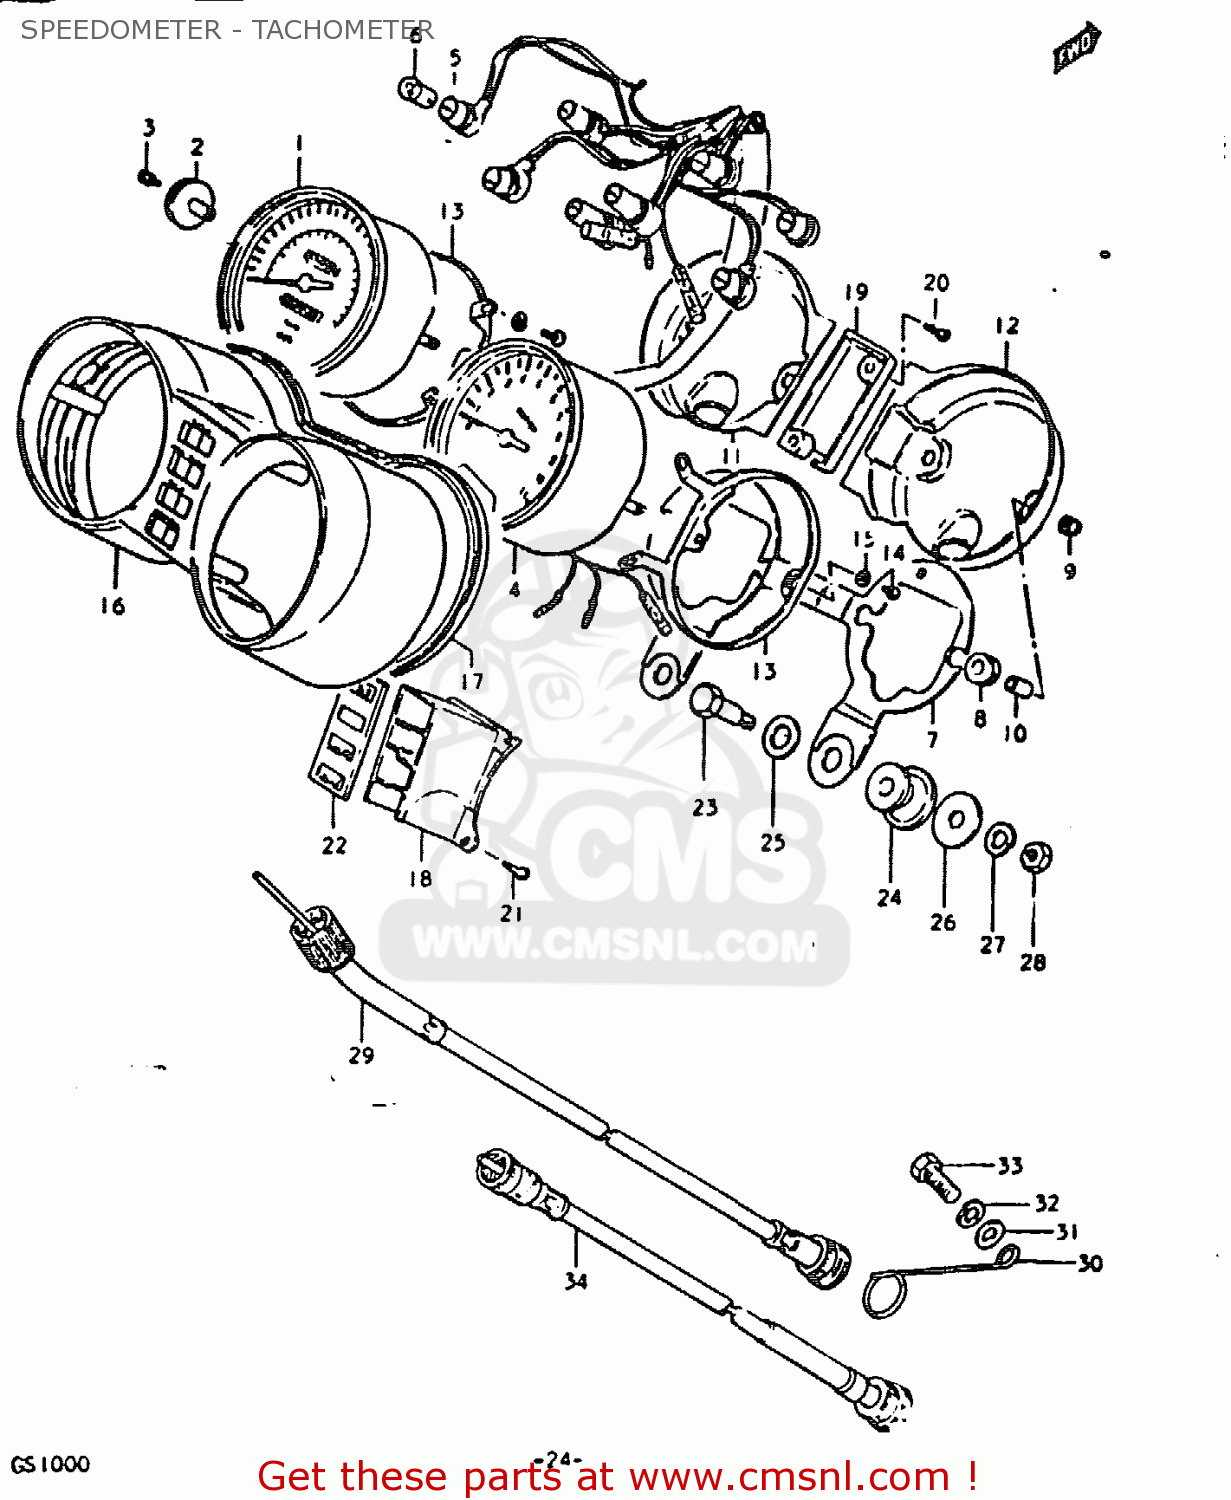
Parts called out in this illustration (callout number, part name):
1	SPEEDOMETER
2	KNOB,TRIP METER
3	SCREW
4	TACHOMETER
5	SOCKET,SPEEDOMETER
6	BULB(12V3.4W,STANLEY,A72A)
7	BRACKET,COMBINATION METER
8	CUSHION,SPEEDOMETER
9	NUT
10	SPACER,SPEEDOMETER
11	COVER,METER,UNDER
12	PLATE,TACHOMETER UNDER
13	HOLDER,METER
14	SCREW
15	LOCK WASHER
16	CASE,METER
17	CUSHION,METER CASE
18	CASE,PILOT BULB
19	PLATE,PILOT BULB CASE
20	SCREW,PILOT CASE
21	SCREW,SPEEDOMETER
22	LENS SET,PILOT LAMP
23	BOLT(8X31)
24	CUSHION,METER
25	WASHER
26	WASHER (8.5X29X1.6)
27	LOCK WASHER
28	NUT
29	CABLE ASSEMBLY,SPEEDOMETER
30	GUIDE,SPEEDOMETER CABLE
31	WASHER 6MM
32	LOCK WASHER
33	BOLT, UPPER
34	CABLE ASSEMBLY,TACHOMETER
